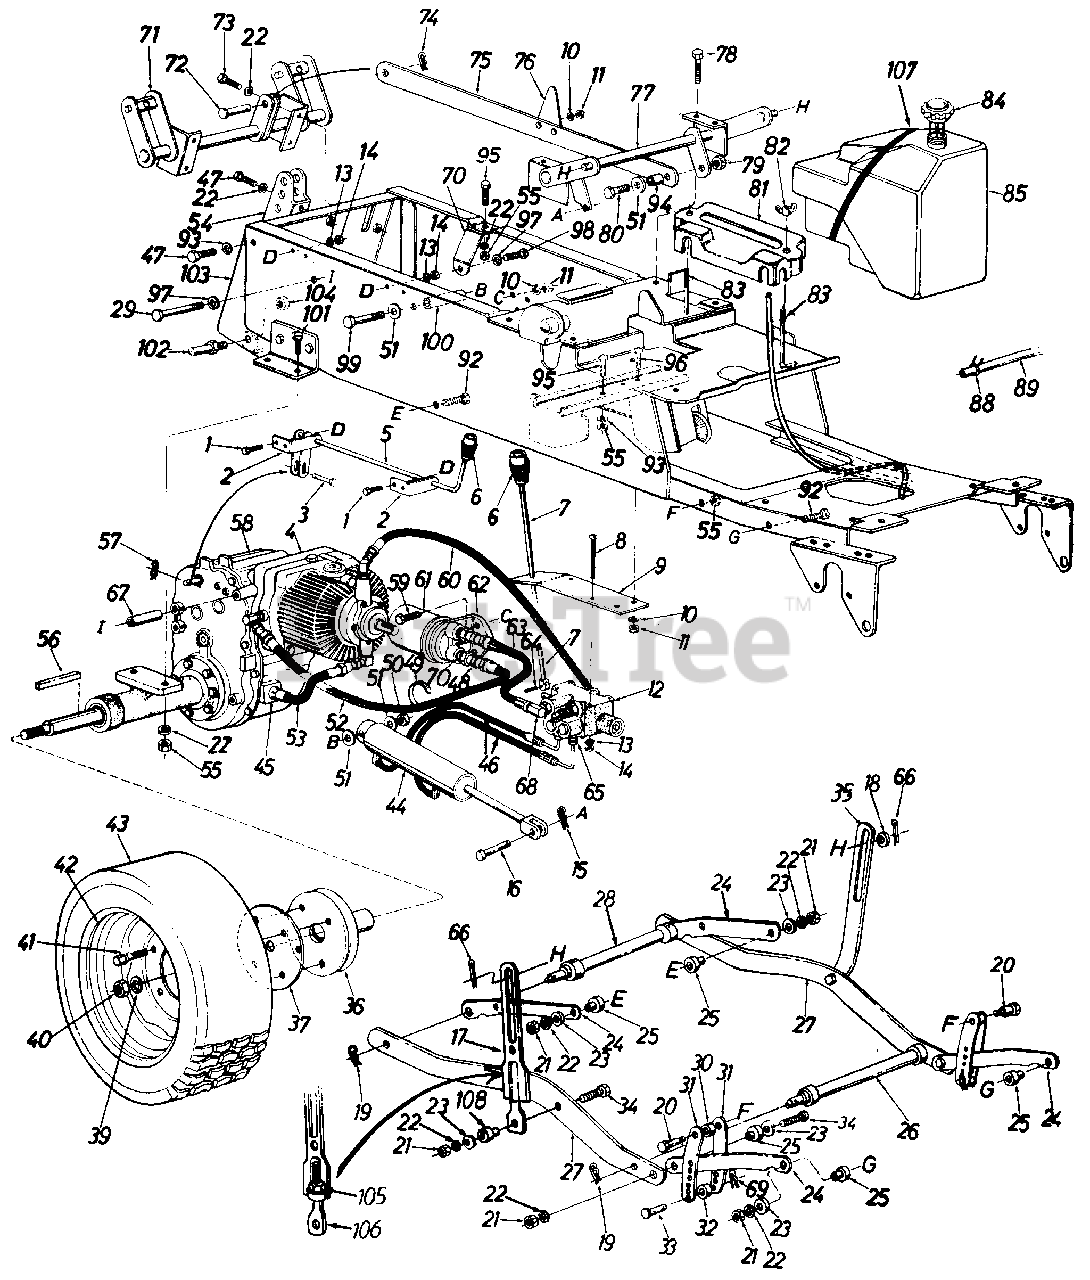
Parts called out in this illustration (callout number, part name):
1	Hex Bolt 1/4-20 x .75" Lg.
4	Hydrostatic Pump Comp.
5	Hi-Lo Control Handle Ass'y.
6	Shift Knob
7	Cylinder Control Handle Ass'y.
8	Truss Mach. Scr. 1/4-20 x 3.00" Lg.
11	Hex Nut 5/16-18 Thd.
12	Valve Ass'y. Comp.
13	L-Wash. 1/4" I.D.
14	Hex Nut 1/4-20 Thd.
15	Hairpin Cotter 1/2" Dia.
16	Clevis Pin 1/2" Dia.
17	Adj. Deck Link
18	Fl-Wash. .62" I.D. x 1.12"
19	Hairpin Cotter
20	Shld. Bolt .498" Dia. x .66"
21	Hex Nut 3/8-24 Thd.
22	L-Wash. 3/8" I.D. - H.D.
23	Fl-Wash. .38" I.D. x 1.00"
26	Cross Shaft Ass'y. - Front
29	Hex Bolt 1/2-13 x 2.75"
30	Collar .50" I.D. x 1.0"
33	Clevis Pin 3/8" Dia.
34	Hex Bolt 3/8-24 x 1.50" Lg. - Grade 5
39	L-Wash. 3/4" I.D.
40	Hex Ins. L-Nut 3/4-16 Thd.
41	Wheel Lug Bolt
44	Hydraulic Cylinder
45	7/8-14 UNF-2A Thd. 5/8 Tube Fitting
46	Valve to Cylinder Hose - 20"
47	Hex Bolt 3/8-16 x .75" Lg. - Grade 5
48	Bushing Reducer 1/2-14 NPTF to 3/8-18 NPTF
49	Cable Tie
50	Hex Jam Nut 1/2-20 Thd.
51	Fl-Wash. .50" I.D. x 1.25
52	Filter Return Hose 24" Lg.
53	Pump Tube Ass'y.
55	Hex Nut 3/8-16 Thd.
56	Sq. Key 1/4" x 1/4" x 2"
57	Hairpin Cotter 1/4" Dia.
58	Peerless Transaxle (See Breakdown)
59	Hex Bolt 5/16-18 x 1.25"
60	Pump to Valve Hose
61	Fram Filter Ass'y. PH-16
62	Filter Base
63	Valve to Filter Hose-8.38"
64	Spring Pin Spiral 1/8" Dia.
65	Flare Adapter
66	Cotter Pin 1/8" Dia. x .10"
67	Spacer
68	Adapter 9/16-18 to 9/16-18
69	Hairpin Cotter
70	Transmission Brace
73	Hex Scr. 3/8-16 x 1.00" Lg. Grade 5
74	Cotter Pin 1/8" dia. x 1.25"
79	Hex Cent. L-Nut 1/2-20 Thd.
80	Hex Scr. 1/2-20 x 1.25" Lg.
81	Battery Cover
82	Wing Nut 1/4-20 Thd.
83	Battery Hold Down Rods
84	Gas Tank Cap
85	Gas Tank Ass'y.
88	Gas Line Clamp 1/2"
89	Gas Line 46" Lg.
92	Hex Scr. 3/8-24 x 1.50" Lg.
93	L-Wash. 3/8" Scr.
94	Push Bar Sleeve
95	Hex Scr. 3/8-16 x 1.00" Lg. - Grade 5
96	Hex Scr. 5/16-18 x .75" Lg.
97	L-Wash. 1/2" Scr.
98	Hex Scr. 1/2-13 x 1.25" Lg.
99	Hex Scr. 1/2-20 x 3-1/2" Lg. - Grade 5
100	Spacer for Cylinder
101	Hex Scr. 3/8-16 x 1.75" Lg.
102	Link Clevis Pin
105	Hex Nut 1/2-13 Thd.
106	Eye Bolt
107	Tie Strap
108	Spacer .385" I.D.
